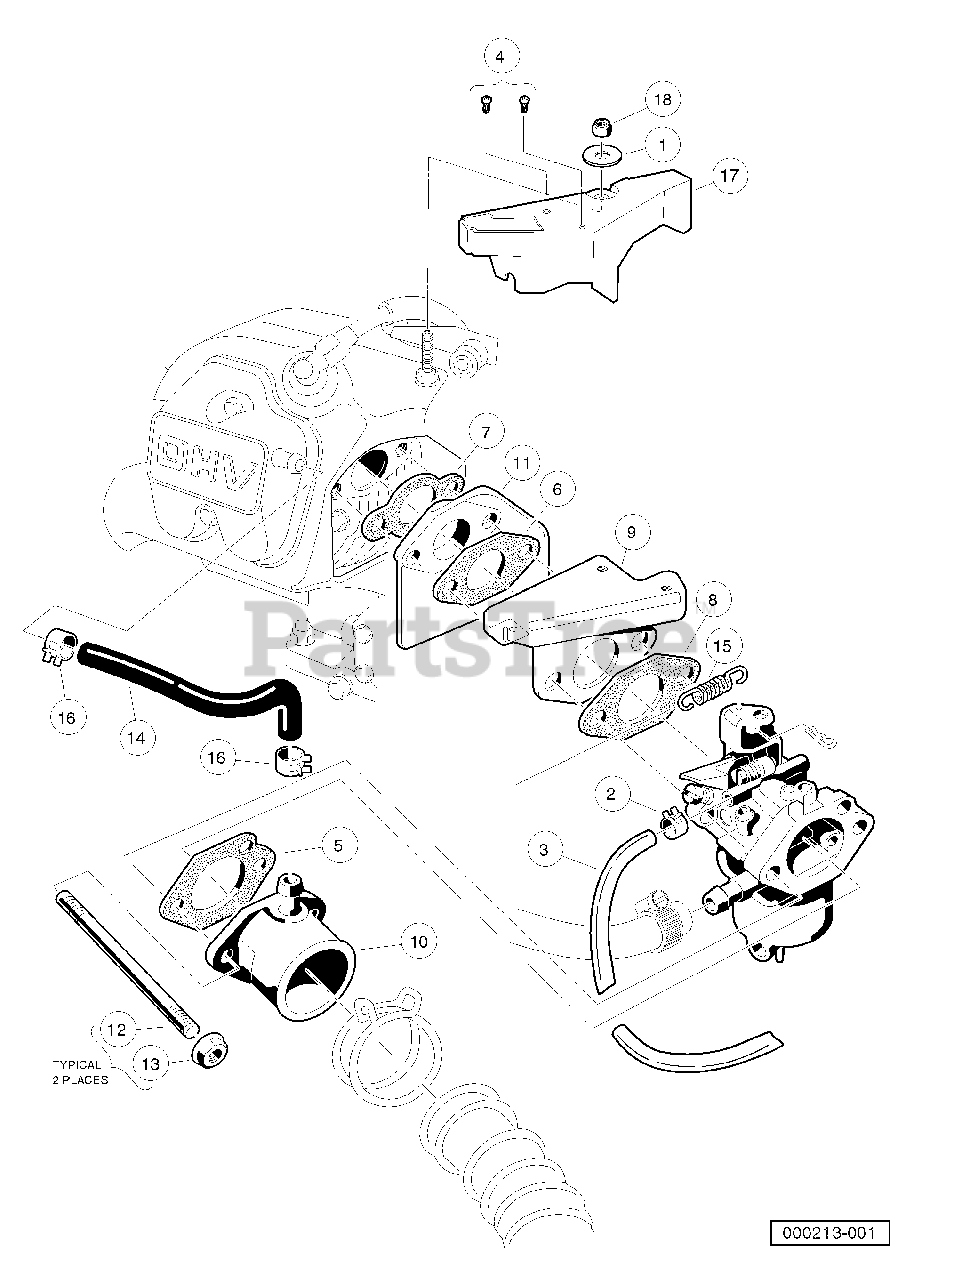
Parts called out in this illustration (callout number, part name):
1	Washer, 5/16 Flat
2	Clamp, 0.301 ID Hose
3	Fuel Line
4	Screw, Pan Hd Tx, Taptite 6-32
5	Gasket, Carb To Intake Manifold
6	Gasket, Insulator
7	Gasket, Engine to Insulator
8	Gasket, Sprg Brkt To Carb OHV
9	Bracket, Throttle Spring Return
10	Pipe, Intake Manifold
11	Insulator, Carburetor
12	Stud, M6-1.00 Two-Ended
14	Tube, Crankcase Vent
15	Spring, Throttle Return
17	Shield, Governor
18	Locknut, M6-1.00 Nylon Insert
